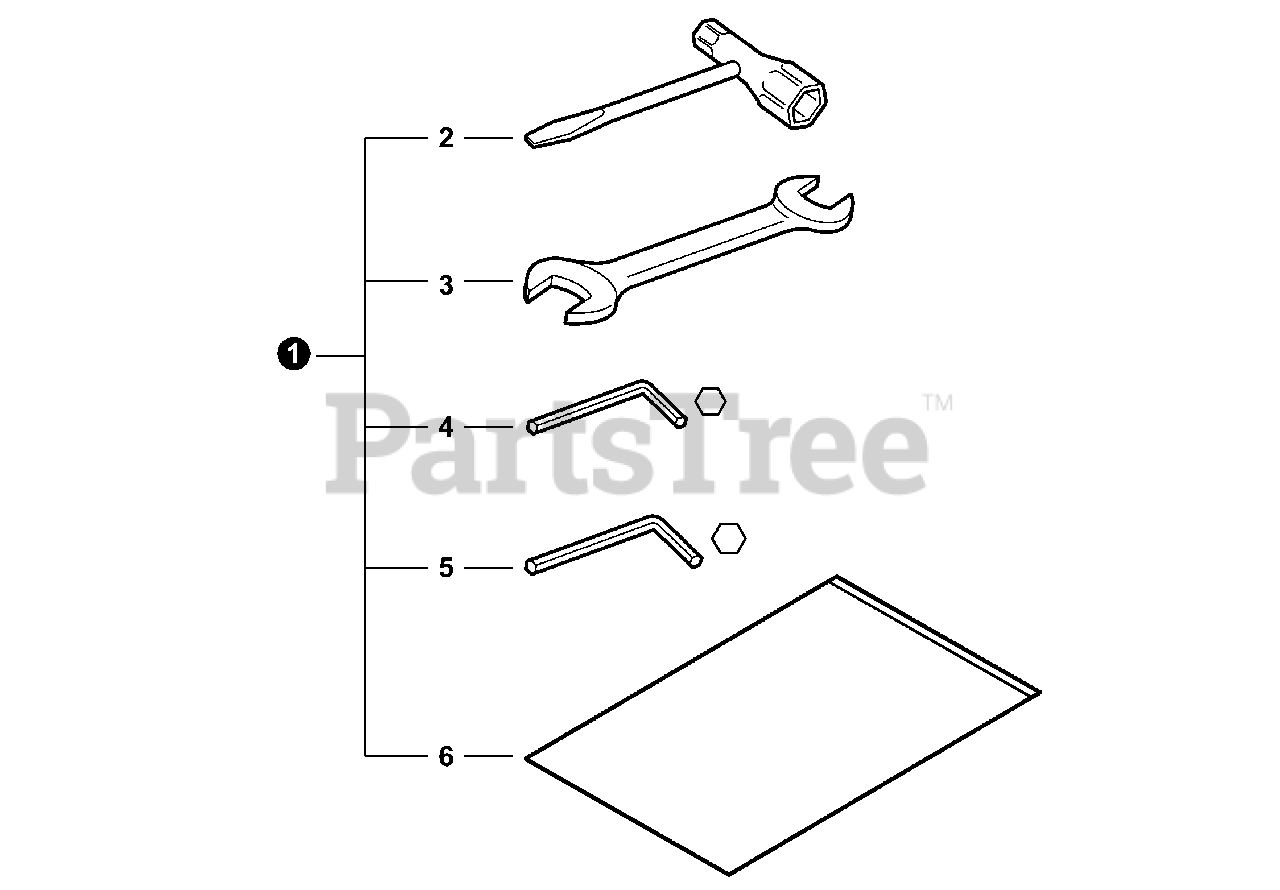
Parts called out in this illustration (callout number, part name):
1	TOOL KIT, SERVICE
2	T-WRENCH 16×13
3	SPANNER 8×10
4	WRENCH, ALLEN 3MM
5	WRENCH, ALLEN 4MM
6	BAG, TOOL
